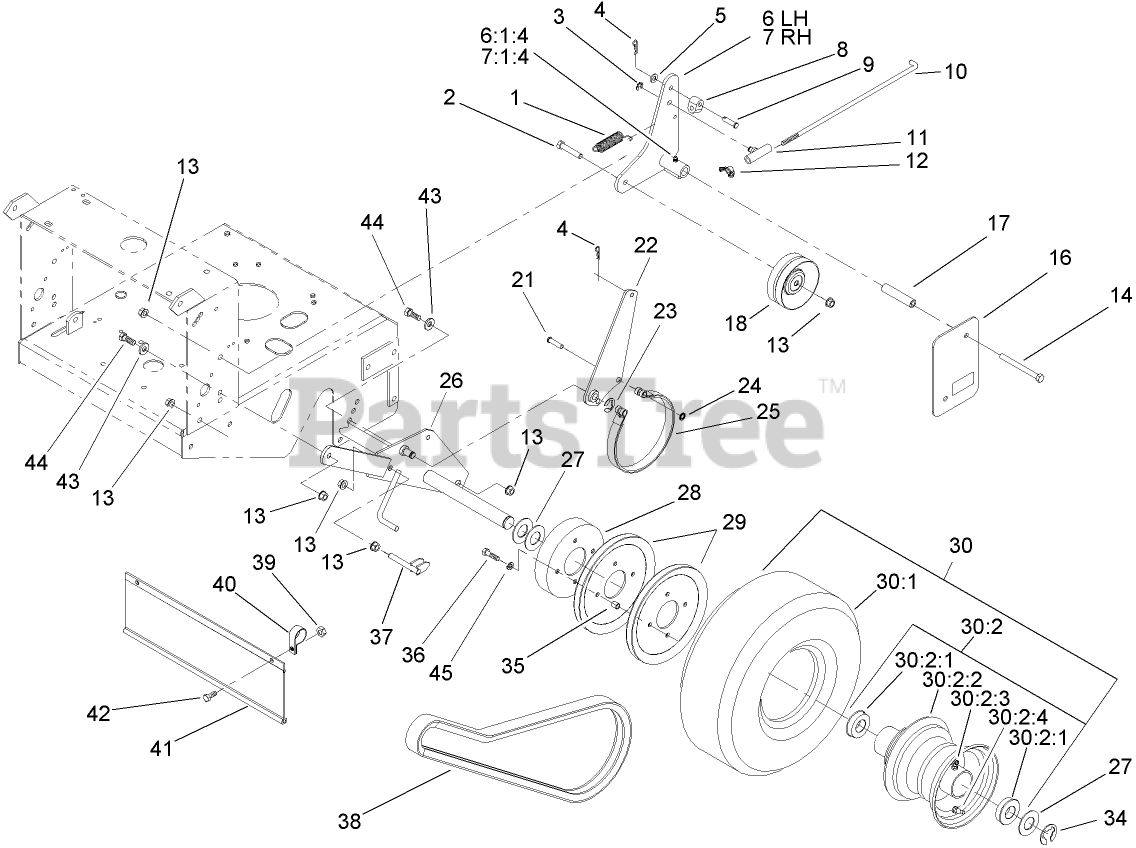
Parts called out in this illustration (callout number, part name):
1	SPRING-EXTENSION
2	SCREW-HH
3	RING-RETAINING
4	PIN-COTTER
5	WASHER-PLAIN
6	RH IDLER ARM ASM
6:1	RH IDLER ARM ASM
6:1:4	FITTING-GREASE
7	LH IDLER ARM ASM
7:1	LH IDLER ARM ASM
7:1:4	FITTING-GREASE
8	FITTING-ROD
9	PIN-CLEVIS
10	ROD-BRAKE
11	SWIVEL-BRAKE
12	WINGNUT-NYLOCK
13	NUT-HHF, WHIZ
14	SCREW-HH
16	SHIELD-WHEEL, DRIVE
17	SPACER-SHIELD
18	IDLER-DRIVE, WHEEL
21	PIN-CLEVIS
22	ARM-BRAKE
23	RING-RETAINING, EXTERNAL
24	NUT-PUSH
25	BAND-BRAKE
27	WASHER-SPACER
28	DRUM-BRAKE
29	SHEAVE-WHEEL, DRIVE
30	WHEEL AND TIRE ASM
30:1	Tire-Turfmaster
30:2	WHEEL AND HUB ASM
30:2:1	BEARING-FLANGED
30:2:2	Rim ASM
30:2:3	Fitting-Grease
30:2:4	Stem-Valve
34	RING-SNAP
35	SPACER-SHEAVE, WHEEL
36	SCREW-HH
37	SCRAPER
38	V-BELT
39	NUT-LOCK, NI
40	CLAMP-R
41	SHIELD-TRAILING
42	SCREW-HH
43	WASHER-BELLEVILLE
44	SCREW-HH
45	WASHER
